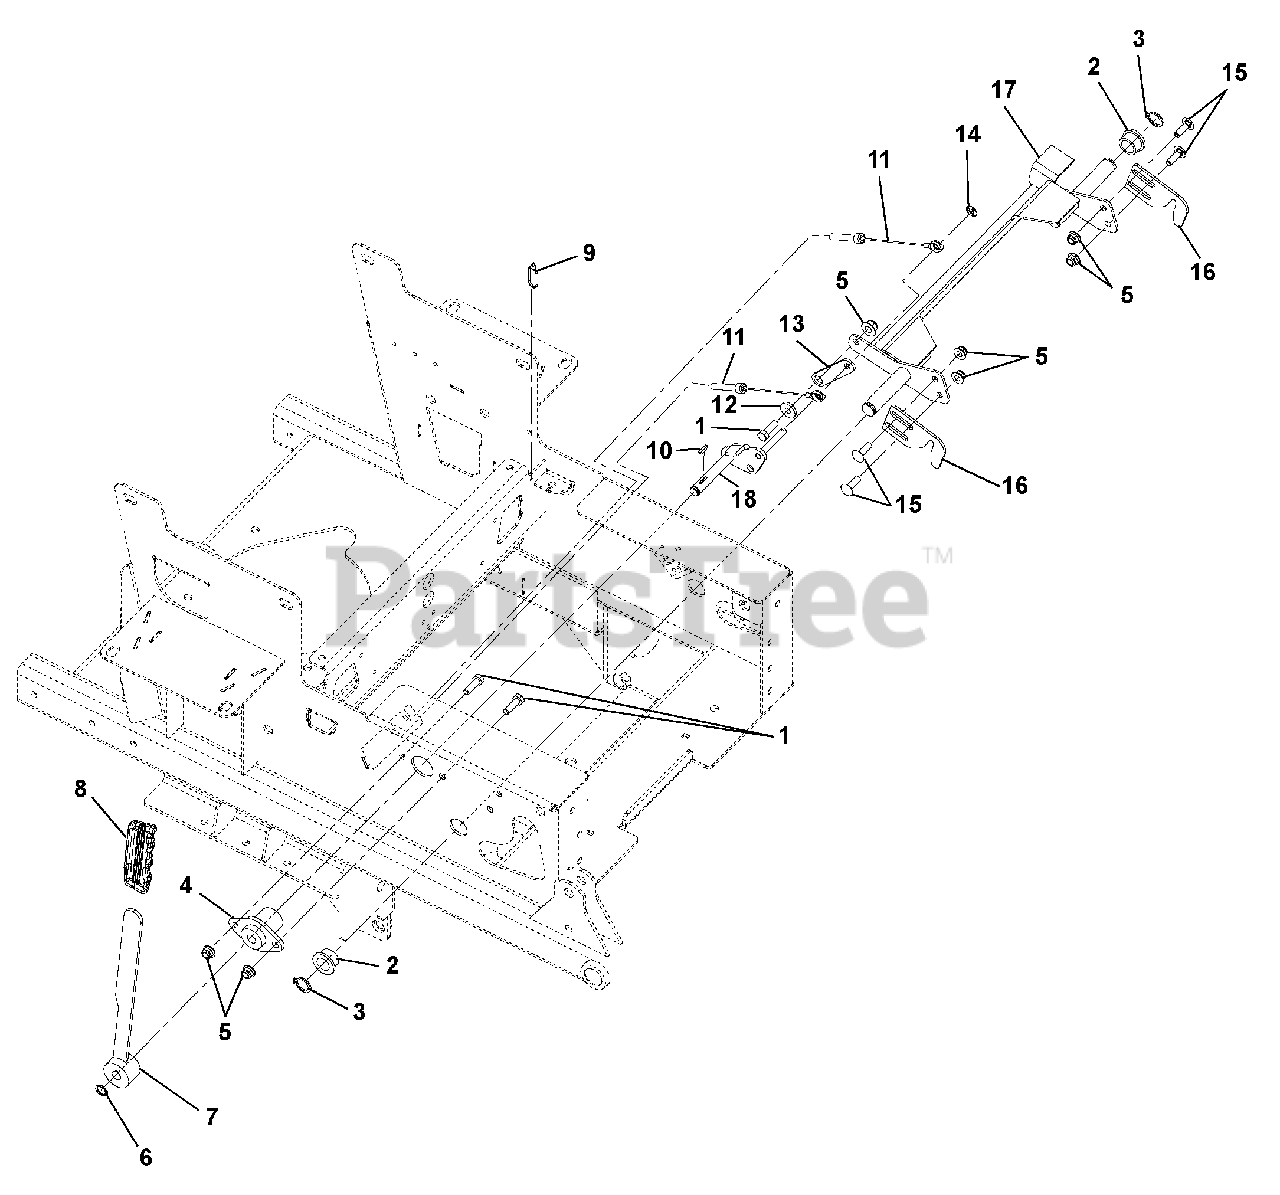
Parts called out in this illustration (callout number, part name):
1	Bolt, Hex .31-18X1.00 Grade 5
2	Bushing, Flange .750 x 1.000 x .625 x 1.250
3	Ring, Retaining-External .689 x .077
4	Bushing, Flanged
5	Nut, .31-18 Nyloc Flange
6	Ring, Retaining-External .500 x .050
7	Weldment, Parking Brake Arm
8	Grip, Parking Brake
9	Cable Tie
10	Key, Woodruff .13 x .63 HRD#5
11	Cable, Brake Actuating
12	Bushing, Flange .325 x .499 x .26 x .88
13	Plate, Neutral Interlock
14	Nut, Push .312
15	Bolt, Round Head Square Neck .31-18 x 1.00 Grade 5
16	Neutral Lock Latch
17	Weldment, 100I Neutral Lock
18	Weldment, Park Brake Arm
